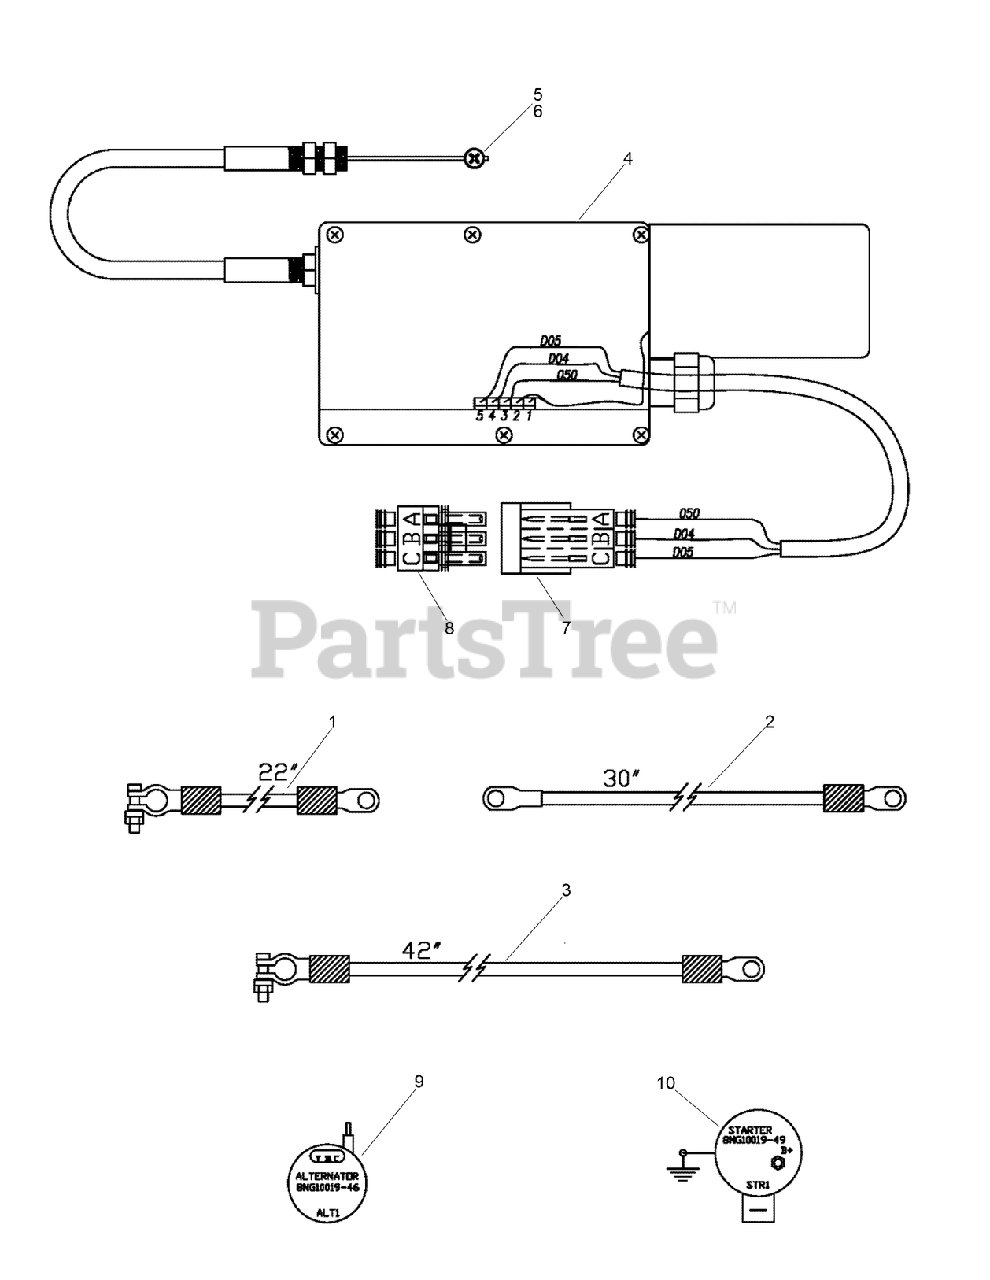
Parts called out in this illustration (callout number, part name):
1	CABLE - Battery, Positive
2	CABLE - Battery, Extension
3	CABLE - Battery, Negative
4	ACTUATOR-THROTTLE
5	THROTTLE PIVOT - 1/4 Shaft
6	PIN - Cotter
7	CONNECTOR - 3 Pin, Weatherpack
8	CONNECTOR - 3 Socket
9	ALTERNATOR
